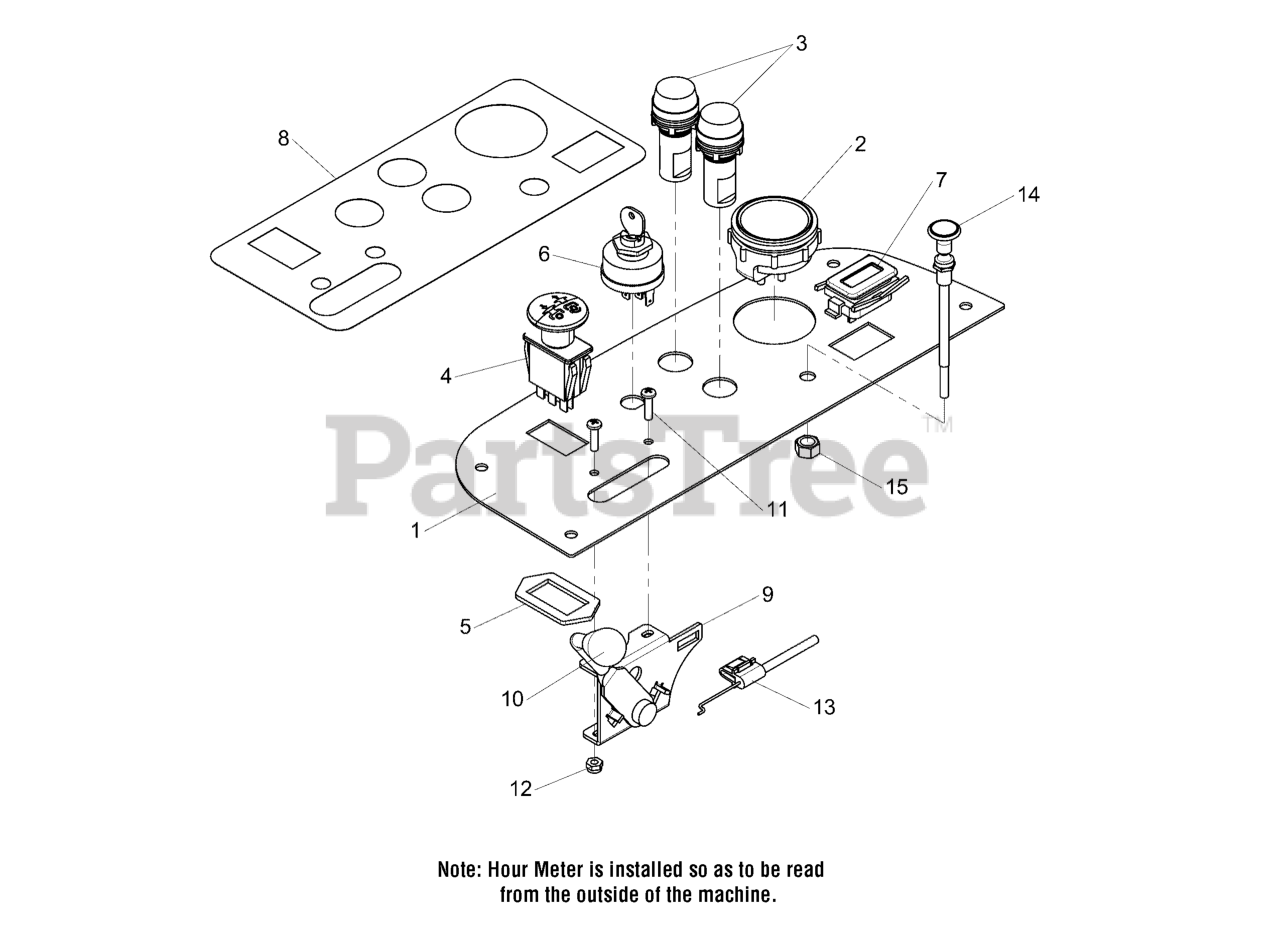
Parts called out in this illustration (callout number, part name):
1	CONTROL PANEL - RH
2	GAUGE, Water Temperature
3	LAMP, Warning, Red
4	SWITCH, BLADE ENGAGEMENT
5	SWITCH RETAINER RING
6	SWITCH, Ignition, Complete
7	HOUR METER
8	DECAL, Control Panel, Gas
9	HANDLE, THROTTLE CONTROL
10	THROTTLE CONTROL HANDLE/KNOB
11	SCREW, #10-24 X 3/4"
12	NUT, #10-24 Hex Nylon Lock
13	CABLE, THROTTLE, 42"
14	CABLE, Choke Control, 39-1/2"
15	NUT, 3/8-24 Hex
